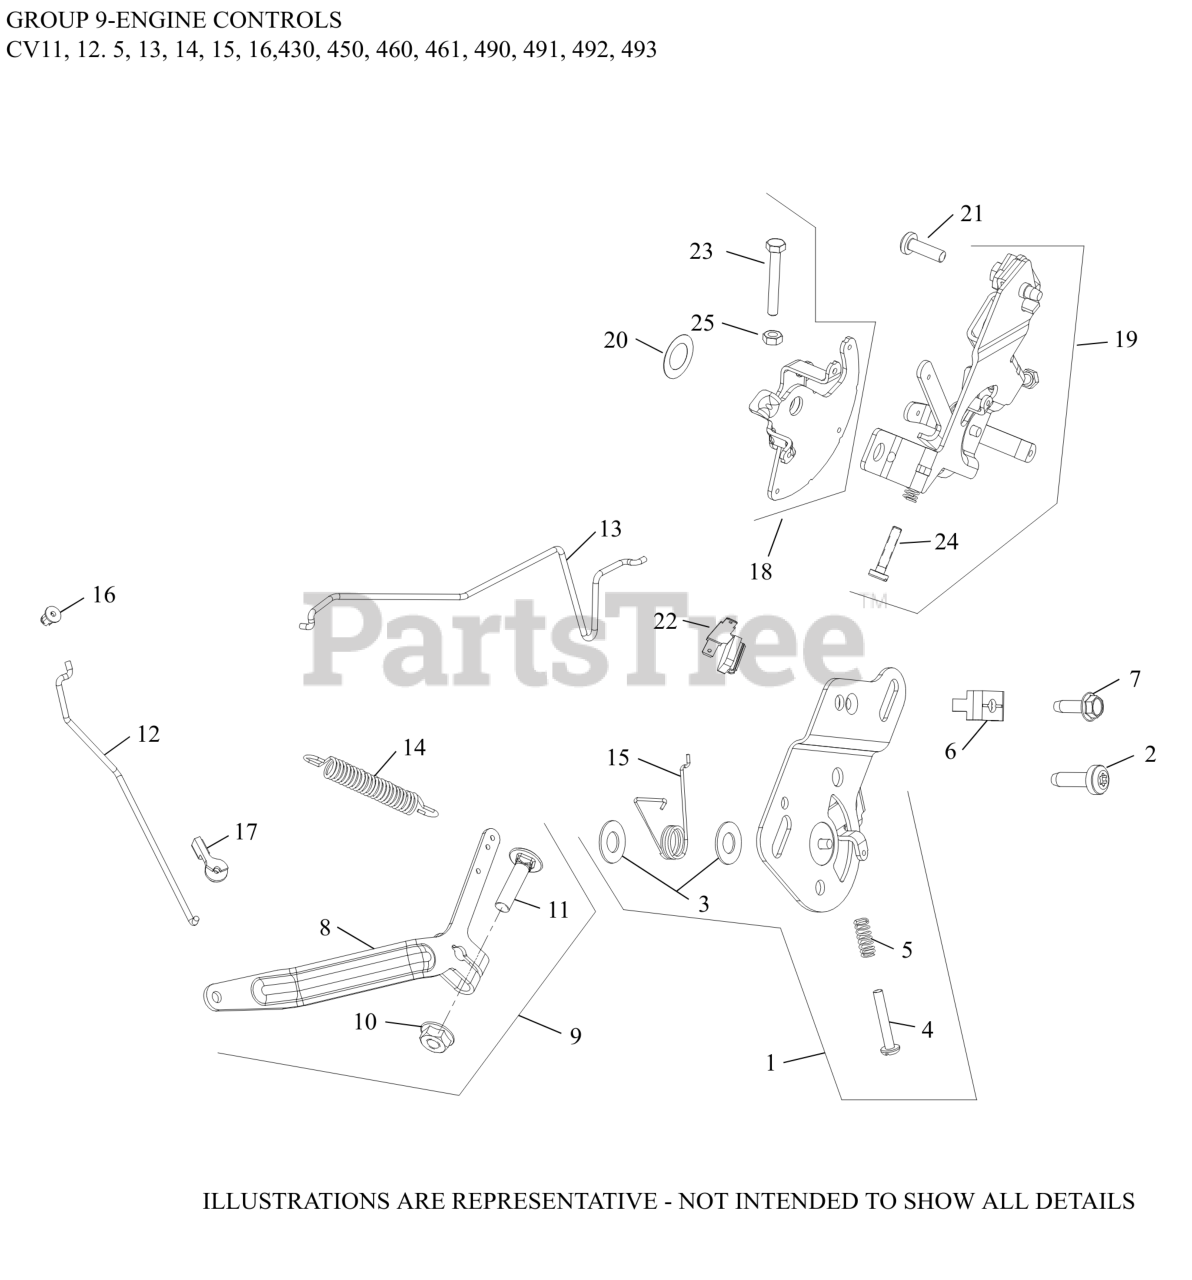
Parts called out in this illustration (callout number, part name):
1	CONTROL, SPEED-DISCONTINUED
2	SCREW, LBD SKT M6x1.0x20-(#25086403S)
3	WASHER, FLAT 9 MM
4	SCREW, PAN HEAD
5	SPRING, SPEED CONTROL (SHORT)
6	CLAMP, CABLE-(#2523753S)
7	SCREW,FLG THD FRM M5X0.8X16-(#25086398S)
8	LEVER, GOVERNOR
9	KIT, GOVERNOR LEVER
10	NUT, FLANGE 1/4-20
11	BOLT, RD HD SQ NCK 1/4-20X1"
12	LINKAGE, THROTTLE
13	LINKAGE, CHOKE-(#DSC)
14	SPRING, GOVERNOR-DISCONTINUED
16	BUSHING, LINKAGE RETAINING
17	BUSHING, THROTTLE LINKAGE
